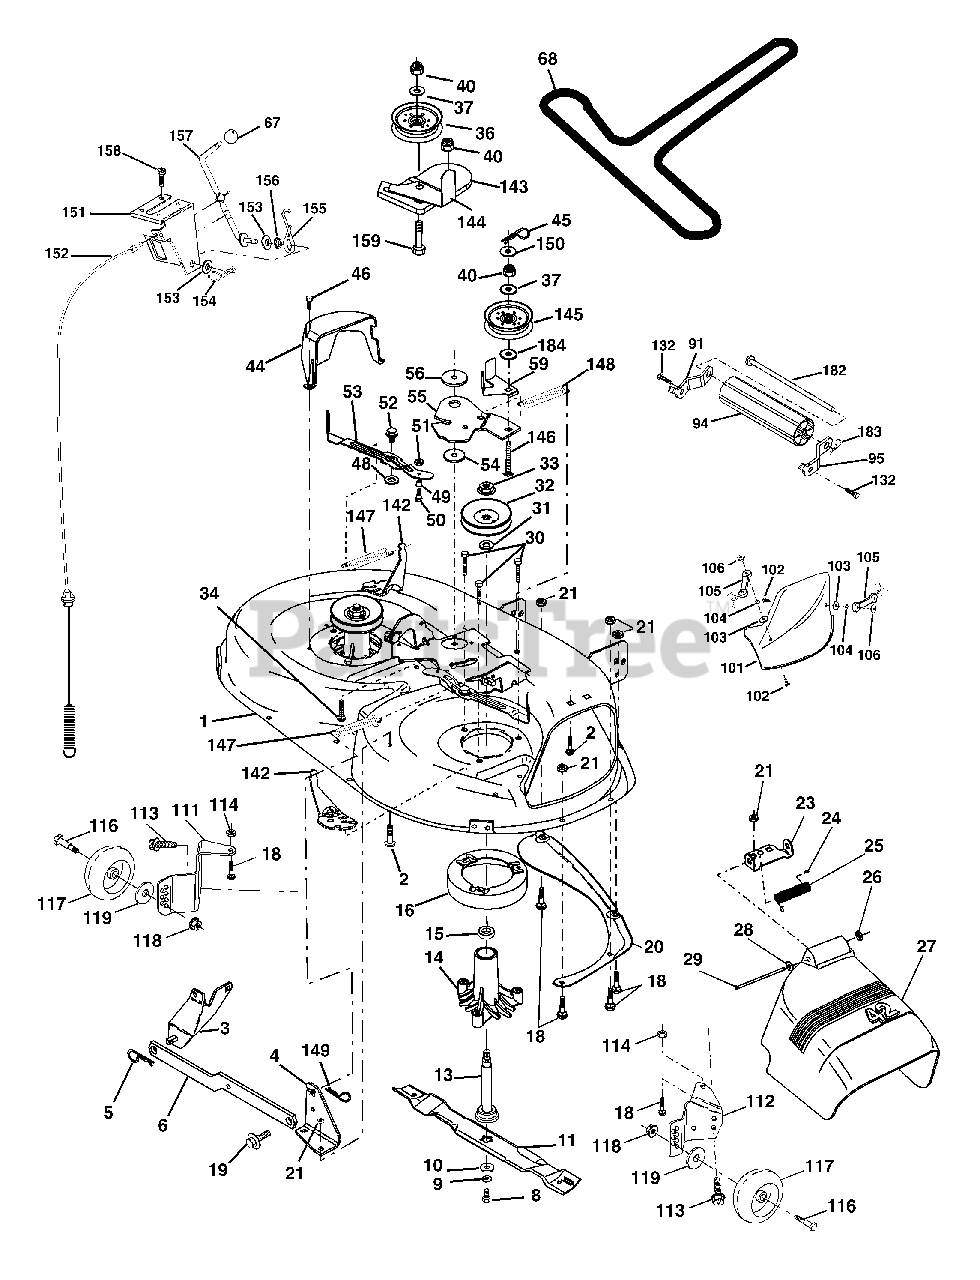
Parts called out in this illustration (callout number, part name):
1	Mower Deck Assembly, 42"
2	Bolt
3	Bracket Asm Fr. Sway Bar 3/42
4	Bracket Asm Deck 42" Sway Bar
5	Retainer Spring
6	Bar Sway Deck
8	Bolt 3/8-24 x 25 Grade 8 patched
9	Washer, Lock
10	Washer, Hardened
11	Blade, 42" Mulching Std
11	Blade, 42" Mulching Premium
11	Blade, 42" Hi-Lift
13	Shaft Assembly, Mandrel, Vented
14	Housing, Mandrel, Vented
15	Bearing, Ball, Mandrel
16	Stripper, Vented Mower Deck
18	Bolt, Carriage 5/16-18 x 5/8
19	Bolt, Shoulder
20	Baffle, Vortex
21	Nut
23	Bracket, Deflector Mower 42"
24	Cap, Sleeve 80 x 112 Blk Mower
25	Spring, Torsion, Deflector 2 52
26	Nut, Push Phos & Oil
27	Shield, Deflector 42" Blk
28	Washer 11/32 x 5/8 x 16 Gauge
29	Rod, Hinge 42" 6 75 W/G
30	Screw Thdrol Washer Head
31	Washer, Spacer Mower Vented
32	Pulley, Mandrel
33	Nut, Toplock Flange
34	Bolt
36	Pulley, Idler, Flat
37	Washer 13/32 x 13/16 x 16 Gauge
40	Nut
44	Guard, Mandrel, LH
45	Retainer
46	Screw, Thdrol 1/4-20 x 5/8 T
48	Washer, Hardened
49	Roller Assembly, Cam Follower
50	Bolt, Shoulder #10-24 Grade 5
51	Locknut
52	Bolt, Shoulder 5/16-18 UNC
53	Arm Assembly, Pad, Brake
54	Washer, Hardened
55	Arm, Idler
56	Spacer, Retainer
59	Guard TUV Idler
67	Knob
68	V-Belt, 42" Mower
91	Bracket Noseroller LH
94	Roller Nose
95	Bracket Noseroller RH
101	Cover Mulching
102	Screw 10-24 x 5/8
103	Washer #10
104	Washer Lock #10
105	Latch Asm.
106	Nut Weld
111	Bracket Wheel Gauge LH
112	Bracket Wheel Gauge RH
113	Screw 3/8-16 x .625
114	Nut Keps 5/16-18 UNC
116	Bolt Shoulder
117	Wheel Gauge
118	Nut 3/8-16
119	Washer 3/8 x 7/8 x 14 Ga.
132	Screw 3/8-16 x 3/4
142	Arm Spring Brake Mower
143	Bracket Arm Idler 42"
144	Keeper Belt 42" Clutch Cable
145	Pulley Idler Flat
146	Bolt Carriage Idler
147	Spring Extension
148	Spring Return Idler
149	Retainer Spring Yellow
150	Washer 9/32 x 3/4 x 16 Ga.
151	Bracket Clutch Cable
152	Clutch Cable 42"
153	Washer Flat 3/8" Type B
154	Spring Retainer
155	Spring Retention LVR CLTCH CAB
156	Spacer Clutch Cable
157	Rod Clutch Cable 3/8"
158	Screw Hex Thd Cut 1/4-20 x 1/2
159	Bolt Rdhd Sqn 3/8-16 UNC x 1-3/4
182	Rod Roller Nose
183	Retainer Spring
184	Washer 13/32 x 7/8 x 10 Ga.
